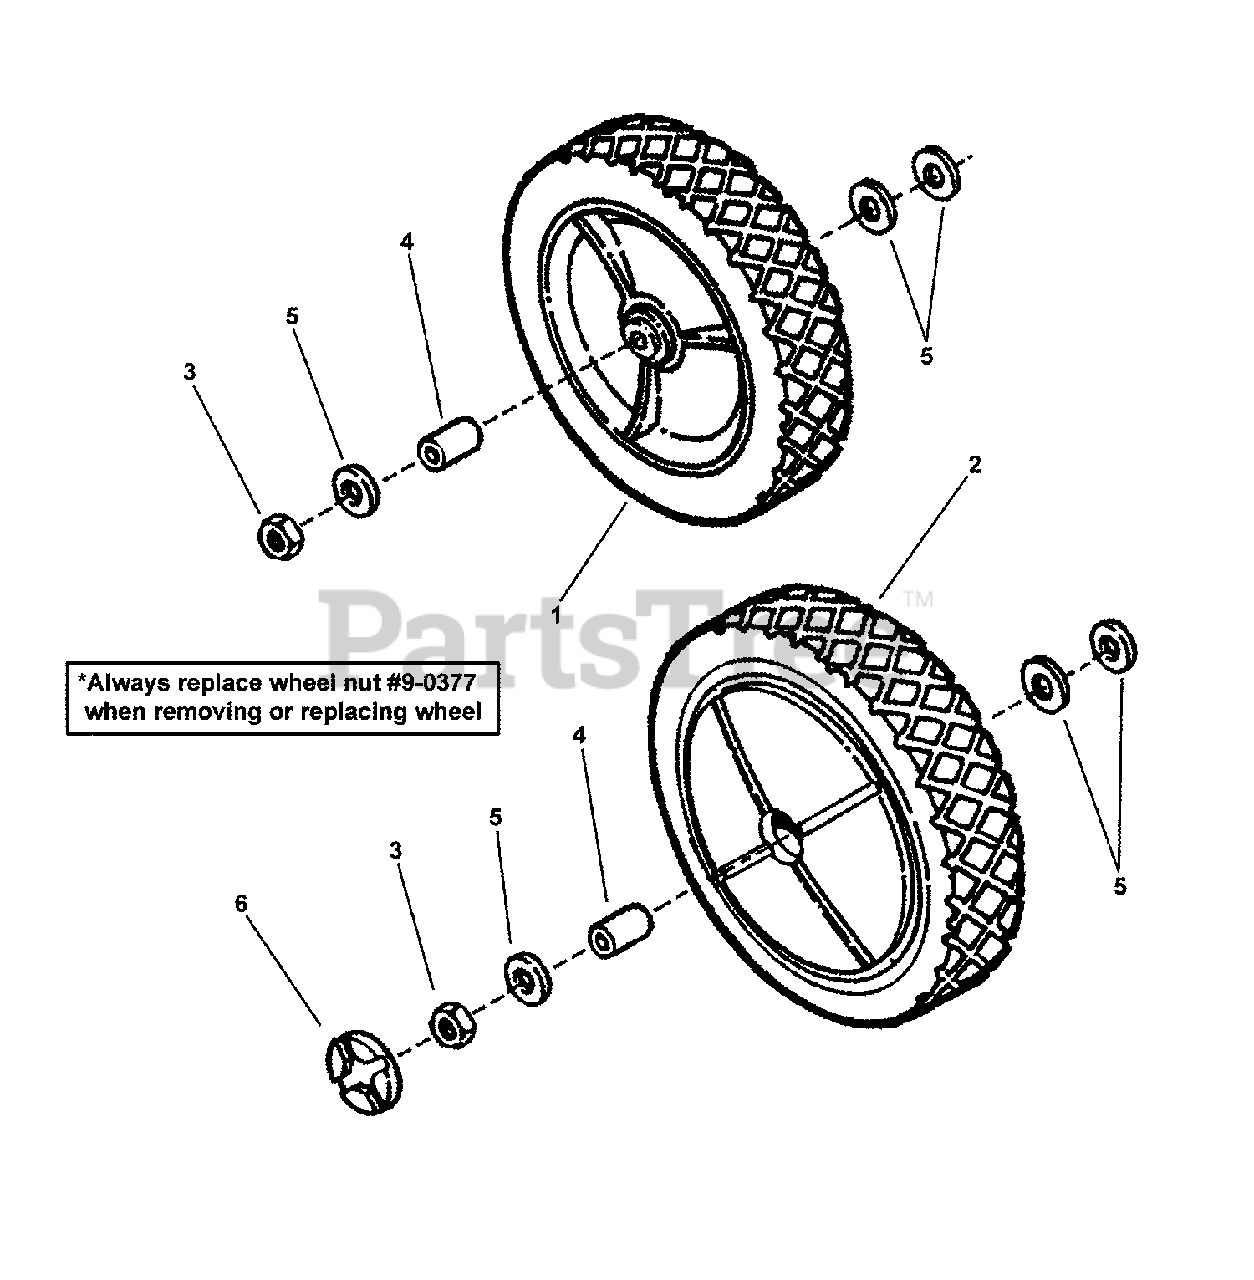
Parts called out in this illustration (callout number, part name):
1	WHEEL, 8 x 1.75 Plastic
2	WHEEL, 8 x 1.75 Plastic
3	NUT, 7/16-20 Hex Center Lock Jam (thin)
4	BUSHING, Axle
5	WASHER, 7/16 x 1" O.D. Flat
6	PLUG, Wheel
